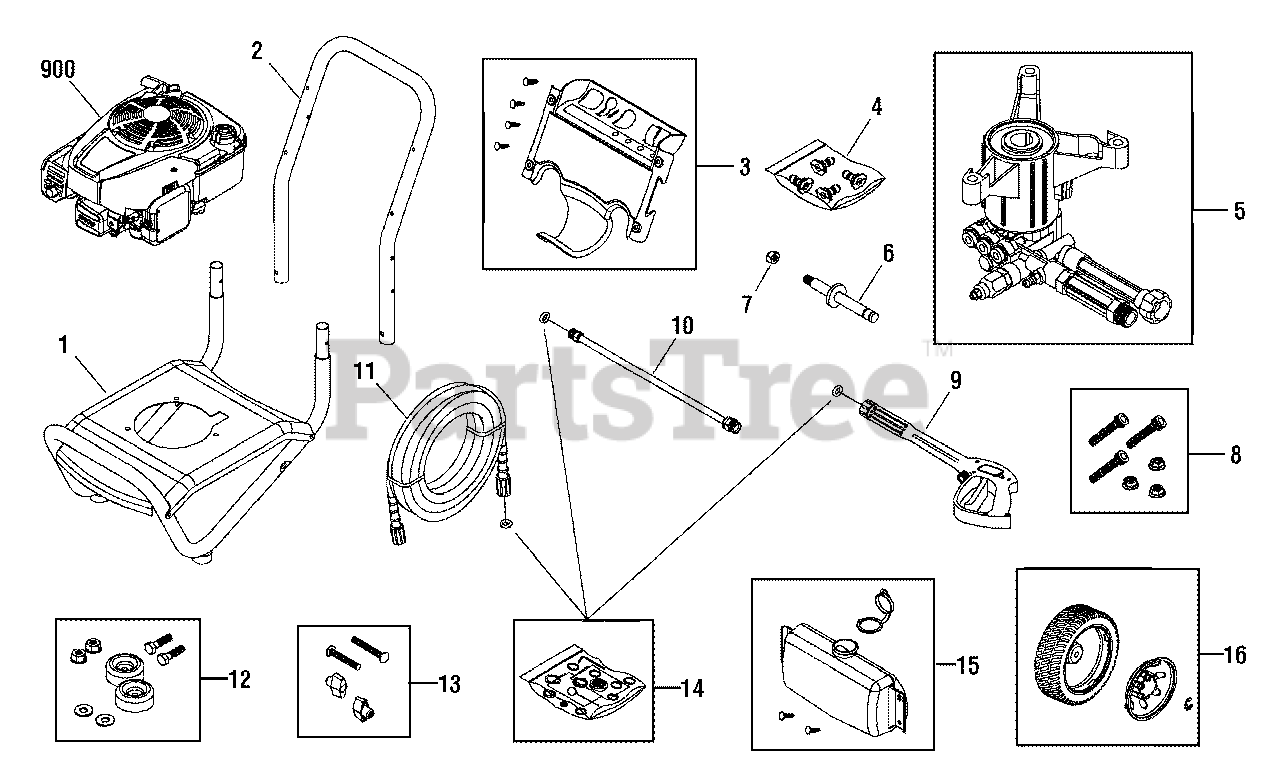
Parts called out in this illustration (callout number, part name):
4	KIT, QC Nozzles
6	AXLE
7	NUT
8	KIT Hardware, Pump Mounting
9	GUN
10	EXTENSION, QC
11	HOSE
12	MOUNT, Vibration
13	KIT, Hardware, Handle
14	KIT, O-Ring
16	KIT, Wheel
900	* ENGINE
